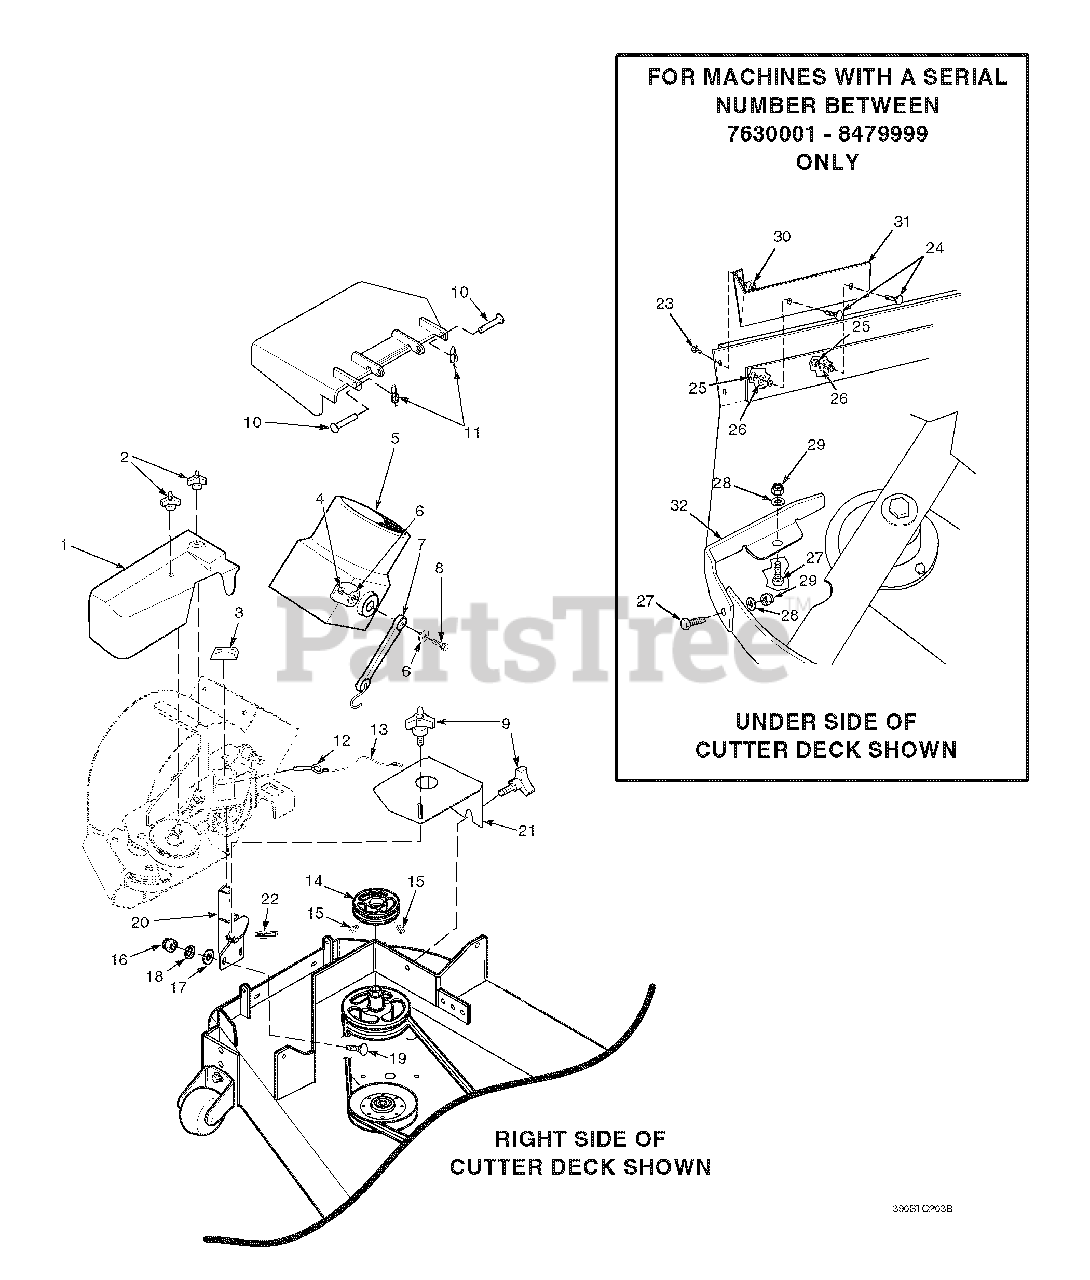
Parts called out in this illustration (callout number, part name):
1	Belt Cover, GC-STC
2	Wingnut, Plastic 3/8" Small
3	Cap, Square Vinyl
4	Nut, Elastic Stop 1/4-20
5	Adapter, Blower GC-STC
6	Flatwasher, 1/4-.312 x .750 x .065
7	Rubber Strap 7-3/4"
8	Bolt, Hex Head 1/4-20 x 1-1/4"
9	Knob W/Stud, 3/8-16 x 1-1/4"
10	Clevis Pin, 5/16 x 1-1/2"
11	Pin, Rue Cotter 5/16 Dia.
12	Pin, Ring 1/2 x 2-1/4"
13	Lanyard
14	Pulley, 4.0" Dia. 1.125 Bore
15	Setscrew, 5/16-18 x 3/8"
16	Nut, Elastic Stop 3/8-16
17	Lockwasher, 3/8"
18	Flatwasher, 3/8-.391 x .938 x .105
19	Bolt, Carr. 3/8-16 x 1-1/4" Grade 5
20	Mounting Post Weldment, Blower
21	Belt Cover
23	Bolt, Hex Head 1/4-20 x 3/4"
24	Bolt, Carriage 3/8-16 x 1"
25	Nut, Elastic Stop 3/8-16
26	Flatwasher, 3/8-.391 x .938 x .105
27	Bolt, Hex Head 5/16-18 x 1"
28	Flatwasher, 5/16-.375 x .875 x .083
29	Nut, Elastic Stop 5/16-18
30	Nut, Serrated Flange 1/4-20
31	Baffle, 48"
32	Baffle, Turbo 48" Deck
